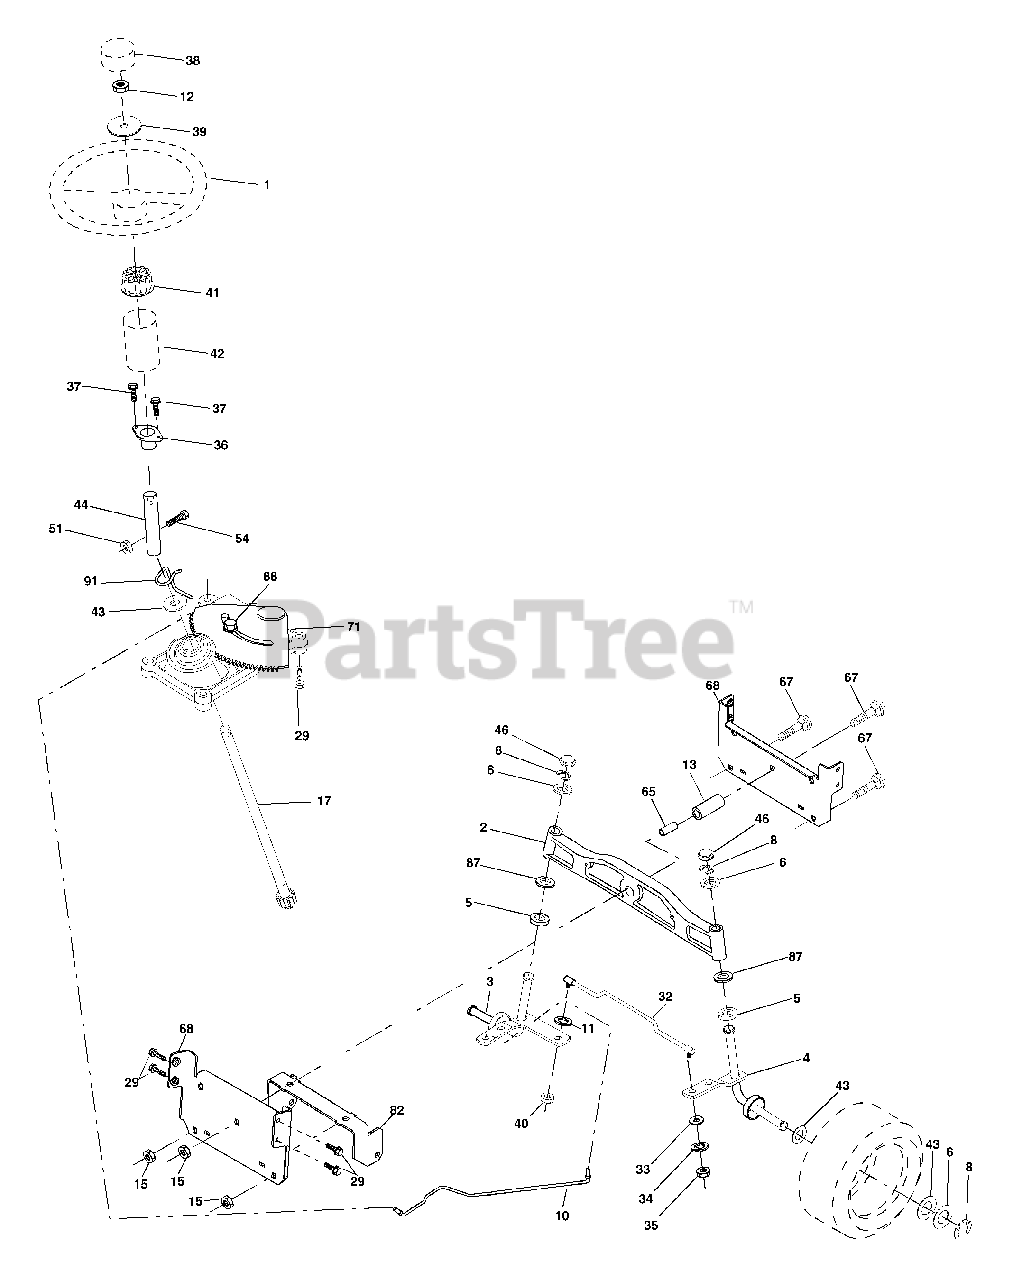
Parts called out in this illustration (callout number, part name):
1	Wheel Steering
2	Axle Asm Cast Iron LT
3	Spindle Asm LH
4	Spindle Asm RH
5	Bearing Race Thrust Harden
6	Washer 25/32 X 1-5/8 X 16 Ga
8	Ring Klip #t5304-75
10	Link Drag
11	Washer Lock Hvy Hlcl Spr 3/8
12	Nut Hex Jam Toplock 1/2-20 UNF
13	Spacer Brg Axle Front
15	Nut Hex Flange Lock
17	Shaft Asm Steering
29	Screw 3/8-16 x .75
32	Rod Tie
33	Washer 11/32 x 3/4 x 16 Ga
34	Washer Lock Hvy Hlcl Spr 5/16
35	Crownlock Nut 5/16-24 Unf
36	Bushing Strg
37	Screw
38	Insert Cap Strg Wh
39	Washer 9/16 X 1 1/20 X 11 Ga
40	Lock nut
41	Adaptor Wheel Strg
42	Boot Steering Dash
43	Washer 25/32 X 1 1/4 X 16 Ga
44	Extension Steering Shaft
46	Cap Spindle Fr Top Blk
51	Nut Crownlock 1/4-28
54	Bolt Hex 1/4-28 UNF x 1-1/4 Gr. 8
65	Spacer Brace Axle
67	Bolt Rdhd Sq 3/8-16 Unc x 2-3/4
68	Axle, Brace
71	Steering Asm
82	Bracket Susp Chassis Front
87	Washer Flat .781 x 1-1/2 x .14
88	Bolt Shoulder 7/16-20 Unc
91	Clip Steering
